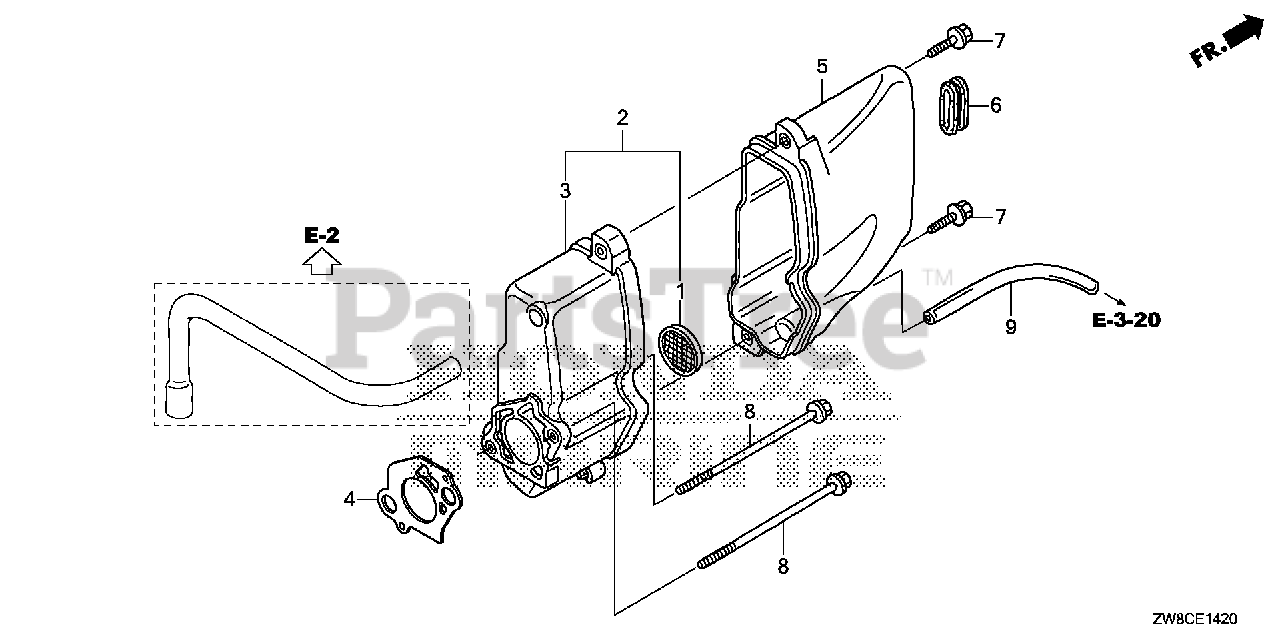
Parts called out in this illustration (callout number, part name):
1	TRAP, FLAME
2	PLATE ASSY., MUFFLER
3	PLATE, MUFFLER
4	GASKET, MUFFLER PLATE
5	COVER, MUFFLER
6	RUBBER A, TANK MOUNTING
7	BOLT, FLANGE (6X22)
8	BOLT, FLANGE (6X98)
9	TUBE, VINYL (3.5X6.5X95)
